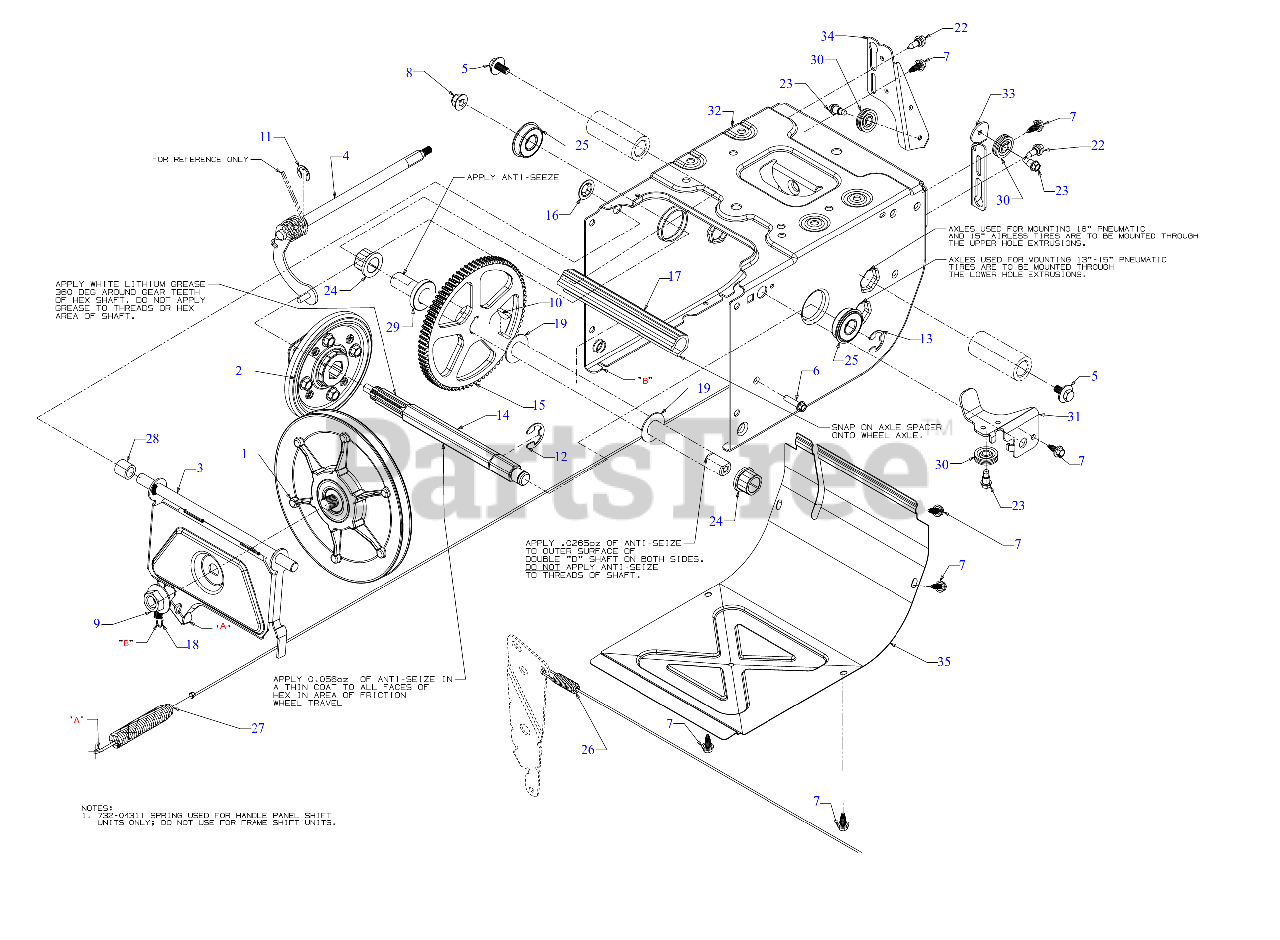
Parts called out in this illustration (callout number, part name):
1	FRICTION WHEEL DISC ASSEMBLY
2	FRICTION WHEEL ASSEMBLY
3	FRICTION WHEEL BRACKET (POWDER BLACK)
4	SHIFT ROD ASSEMBLY
5	SCREW 5/16-24 x .750 GR5
6	SCREW 1/4-20 x 1.00
7	SCREW 1/4-20X.625
9	FLANGE NUT 5/8-18
10	KEY-HI-PRO #9-3/16X3/4 DIA
11	E-RING FOR .500 SHAFT
12	RETAINING RING
13	E-RING
14	HEX SHAFT .8125 HEX 7 TOOTH
15	80-TOOTH GEAR
16	PUSH CAP
17	SPACER (.75" x .05" x 7.65")
18	EXTENSION SPRING
19	FLAT WASHER .760ID X1.49OD x .06
22	SHOULDER SCREW
23	SHOULDER SCREW
24	FLANGE BEARING
25	BALL BEARING W/RET
26	AUGER DRIVE CABLE 47.48"
27	WHEEL DRIVE CABLE 44.955"
28	SPACER-.513 ID x .703 OD x .69
29	AXLE SPACER
30	CABLE GUIDE ROLLER
31	AUGER CABLE BRACKET
33	AUGER CABLE GUIDE BRACKET
34	GUIDE BRACKET
